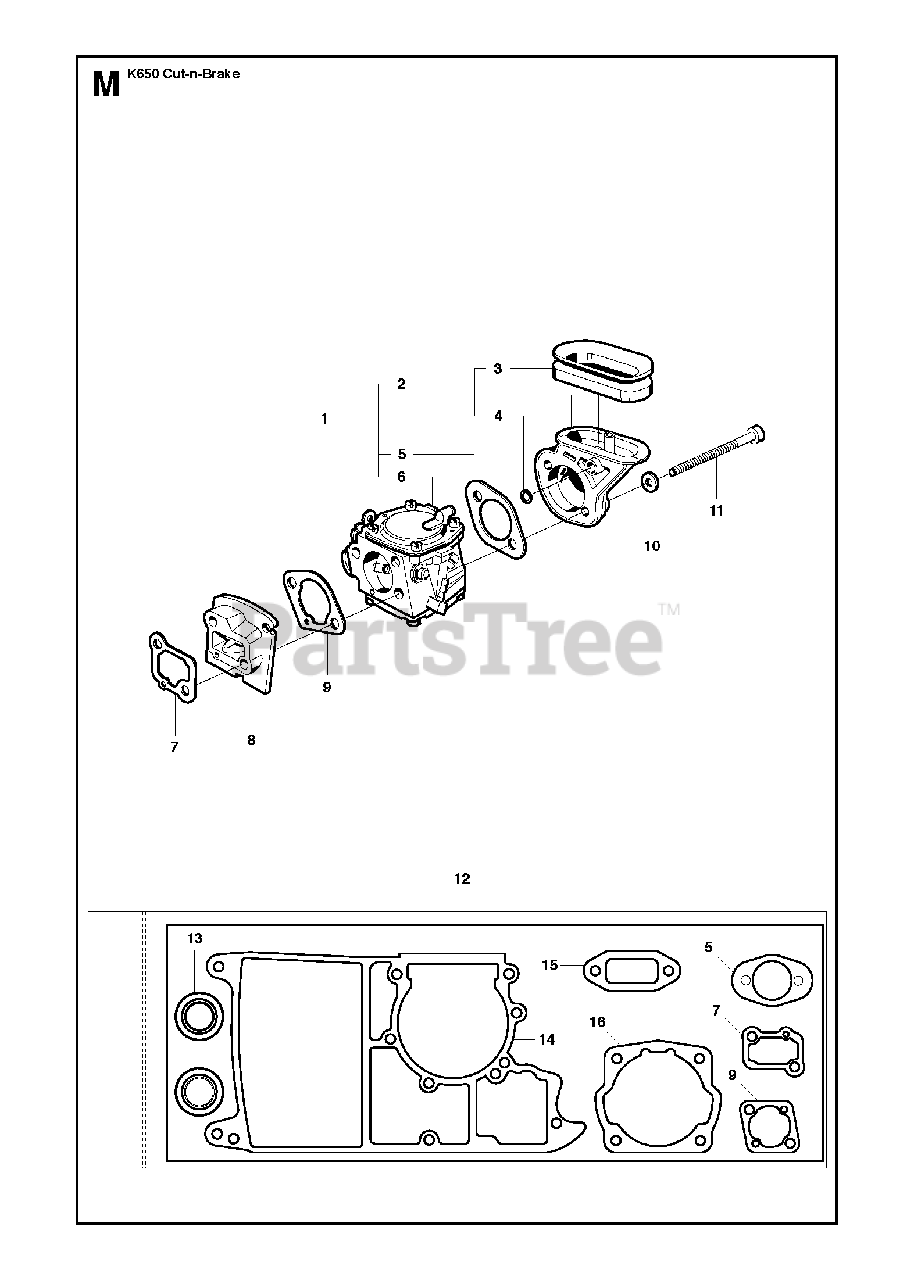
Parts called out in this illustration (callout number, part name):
1	CARBURETTORIncl. 2, 5, 6
5	GASKETGasket Kit 12
6	CARBURETTORTillotson HS 175N
7	GASKETGasket Kit 12
8	INSULATING FLANGE506 32 02-01
9	GASKETGasket Kit 12
13	SEALING RING
